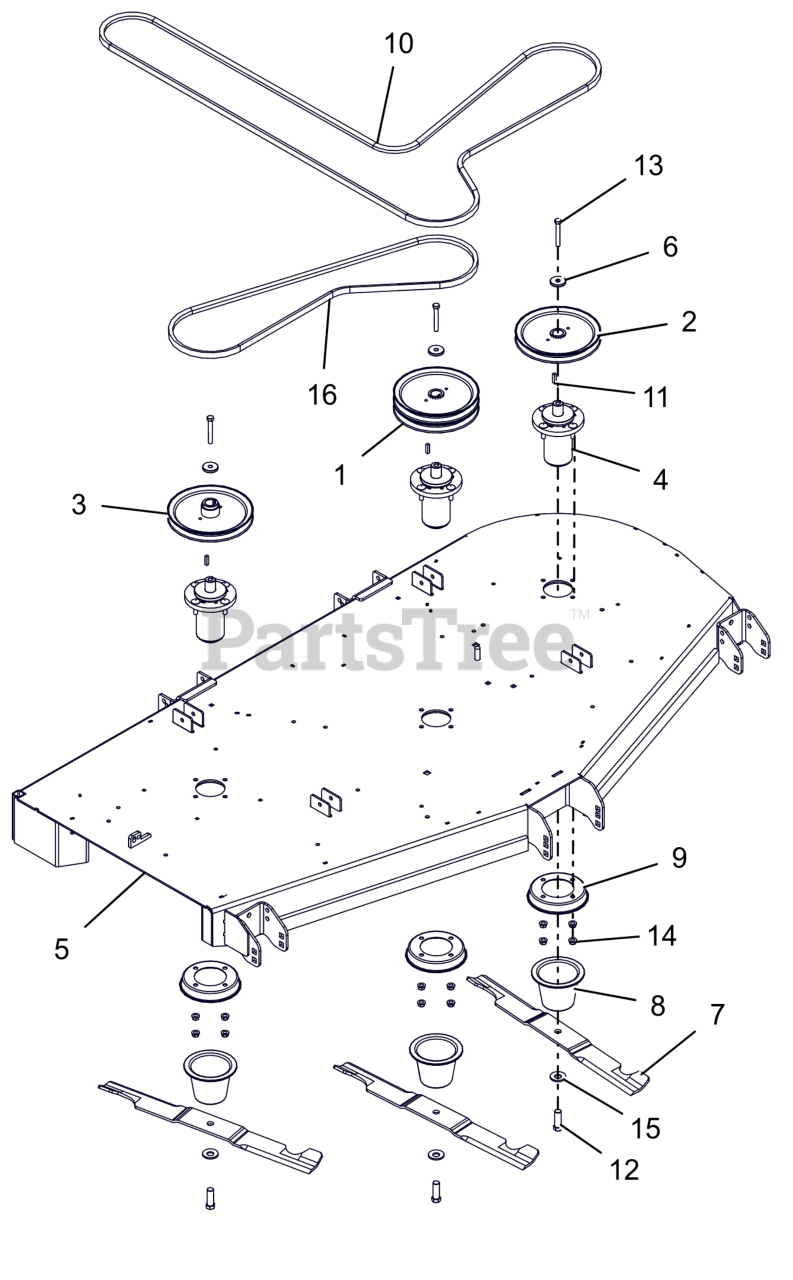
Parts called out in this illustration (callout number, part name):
1	SHEAVE-DOUBLE 1.00"IDX8.25"OD
2	SHEAVE-SINGLE 1.00"IDX8.25"OD
3	SHV-SINGLE 1.00"ID X 8.25"OD
4	ASM, MAINT FREE ALUM SPINDLE
5	WLDMT, 72" SIDE DISCHARGE DECK
6	RETAINER, SHEAVE
7	BLADE, 72"
8	GUARD, SPINDLE LOWER
9	GUARD, SPINDLE TOP
10	V-BELT, HB WRAPPED
11	KEY, SQ .25X.25X1.00 RC 40-50
12	BLT, HEX .62-18X1.75 G8 ZCC
13	BLT, HEX .38-16X2.75 G8 ZCC
14	NUT-LK-CTR-FLG .375-16 GF ZCC
15	WSHR-BLVL .669X1.535X.138
16	V-BELT, B-COGGED
